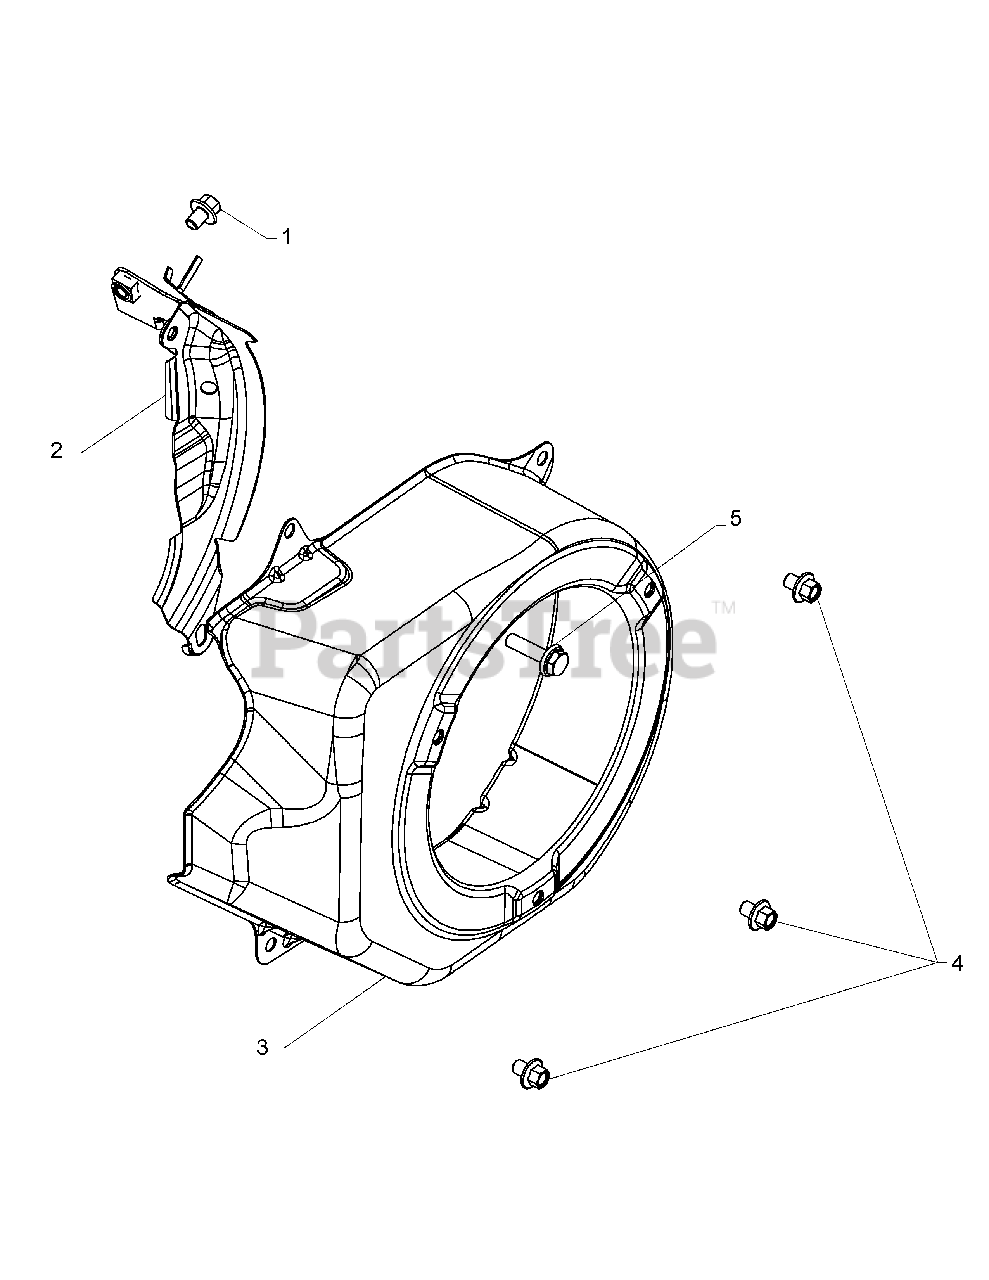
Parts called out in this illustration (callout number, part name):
1	Hex Flange Screw
2	Lower Blower Housing Cover Assembly
3	Blower Housing Assembly
5	Screw, M6 x 22
